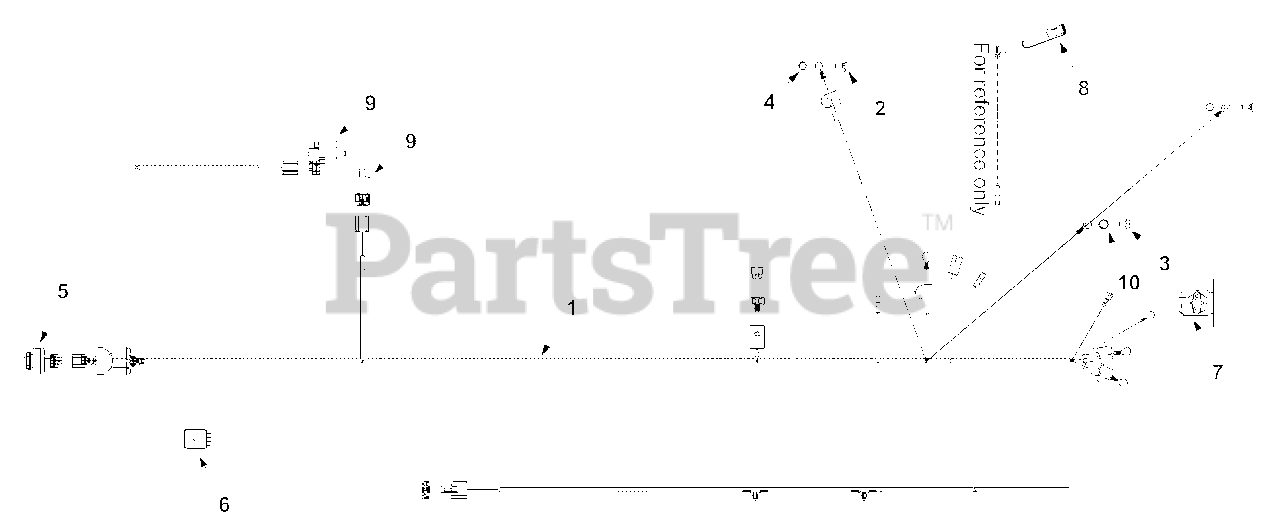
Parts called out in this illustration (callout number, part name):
1	Harness Assembly w/o
2	Carriage Screw 1/4-20 x 0.62"
3	D Screw 5/16-18 x 0.625"
4	Sems Nut 1/4-20
5	Ignition Switch: 5 Pin
6	Seat Switch
7	Solenoid 12 volt, 100 amp.
8	Spring Switch
9	Switch: Interlock
10	Lock Washer 5/16
